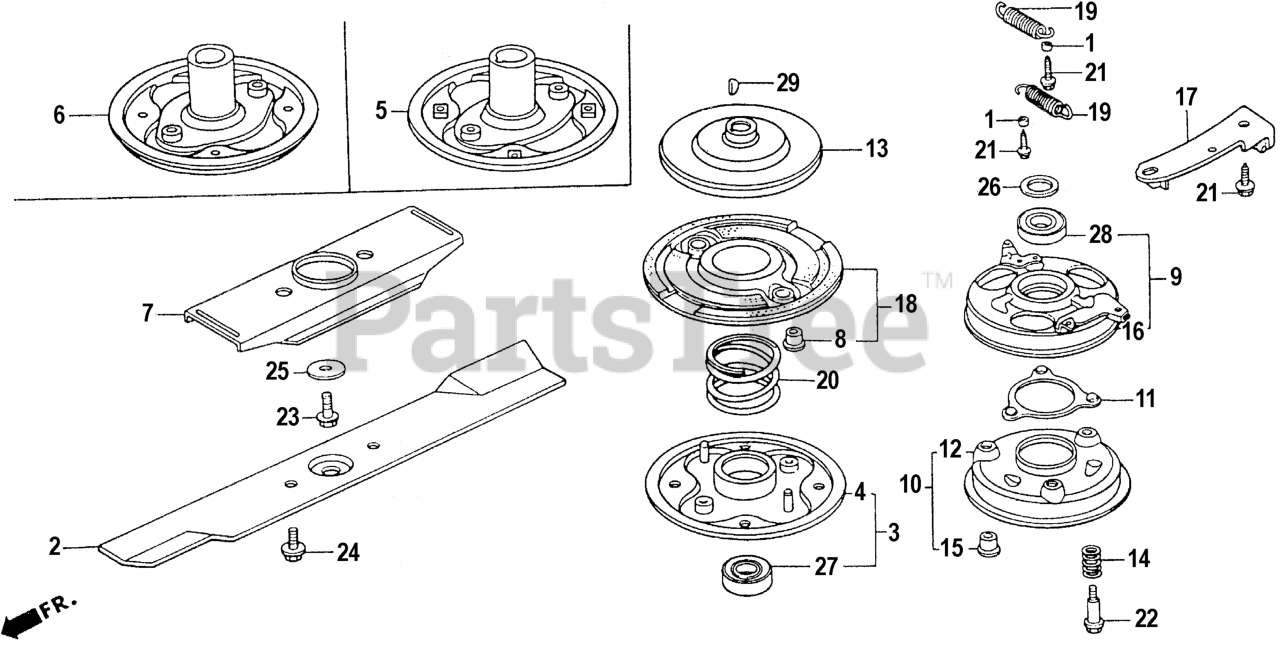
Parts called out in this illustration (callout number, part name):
1	COLLAR, FAN
2	BLADE, ROTARY (21")
3	HOLDER ASSY., BLADE
4	HOLDER, BLADE
7	HOLDER, BLADE
8	BUSH, BLADE HOLDER
9	PLATE ASSY., BALL CONTROL
11	RETAINER, BALL
12	DISK, BRAKE
13	DISK, DRIVE
14	SPRING, BRAKE HOLDER
15	BUSH, BRAKE HOLDER
16	PLATE, BALL CONTROL
17	PLATE, CABLE HOOK
18	DISK, DRIVEN
19	SPRING, CLUTCH RETURN (53.0MM)
20	SPRING, CLUTCH (36.6MM)
21	BOLT, FLANGE (6X14)
22	BOLT, SPECIAL (6MM)
23	BOLT, HEX. (10X25)
24	BOLT, HEX. (10X20)
25	WASHER (10MM)
26	WASHER, THRUST (22X32X3)
27	BEARING, RADIAL BALL (6204)
28	BEARING, RADIAL BALL (60/22UU)
29	KEY, WOODRUFF (16X15)
